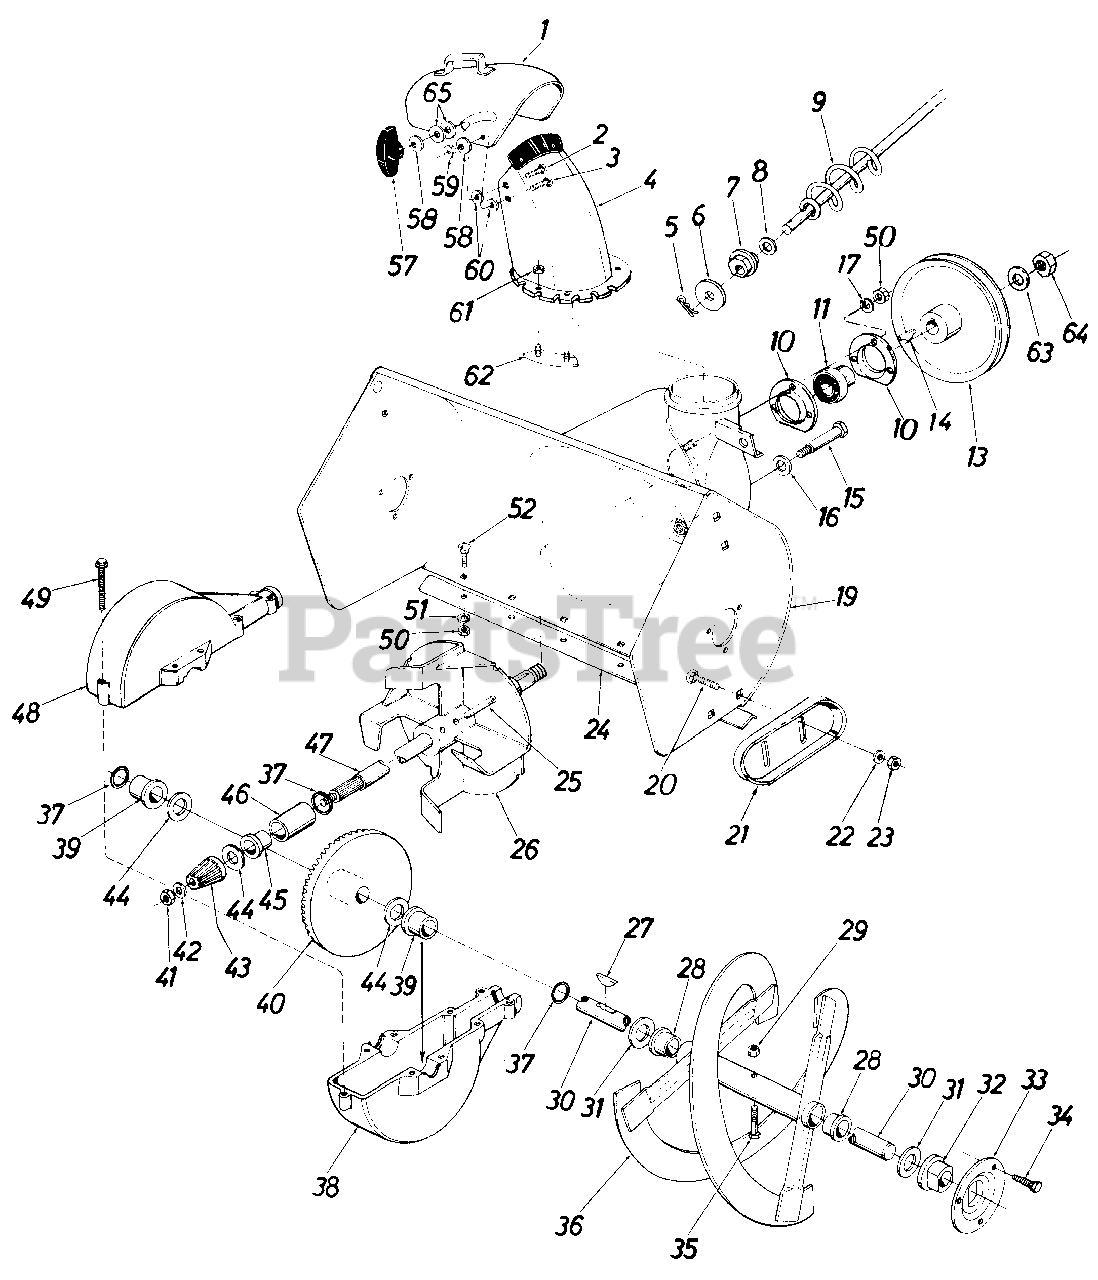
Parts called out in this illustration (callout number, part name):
1	Top Chute Ass'y.
2	Carriage Bolt 5/16-18 x 1.00" Lg.*
3	Carriage Bolt 5/16-18 x .62" Lg.*
4	Chute Ass'y.
6	Fl-Wash. .390 I.D. x 1.50" O.D.
8	Fl-Wash. .385 0 I.D. x .62" O.D.
9	Chute Crank Ass'y.
10	Bearing Housing
11	Self-Align Brg. w/ Collar .75" I .D.
13	1/2" "V"-Pulley .625" I.D. x 7.50" O.D.
14	#61 Hi-Pro Key 3/16" x 5/8" Dia.
15	Shld. Bolt .50" Dia. x 2.11" Lg.
16	Bell-Wash. .40" I.D. x .88" O.D. x .06
17	L-Wash. 5/16" I.D.*
19	24" Blower Housing Ass'y.
20	Carriage Bolt 3/8-16 x .62" Lg.*
21	Slide Shoe
22	Bell-Wash. 3/8" I.D.
23	Hex Jam Nut 3/8-16 Thd.
26	11" Dia. Blower Fan Ass'y.
27	#9 Hi-Pro Key 3/16 x 314" Dia.
28	Flange Brg. .75" I.D. x .88" O.D. x .62
29	Hex Ins. L-Nut 5/16-18
30	Spiral Axle
31	Fl-Wash. .75" I.D. x 1.50" O.D. x .06
32	Flange Brg. w/ Flats .755"
33	Bearing Housing
34	Hex Wash. Hd. Self-Tap Scr. 5/16-24 x .50" Lg.
35	Hex Bolt 5/16-18 x 1.50" Lg.
36	24" Spiral Ass'y. L.H.
37	"O"-Ring 3/4" I.D.
38	Bevel Gear Housing Lower Half
39	Plastic Flange Brg. .755" I.D.
41	Hex Cent. L-Nut 5/16-24 Thd.
42	Fl-Wash. .34" I.D. x .62 " O.D. x .06
43	Pinion Gear
44	Fl-Wash. .75" I.D. x 1.25" O.D. x .06
45	Flange Brg. .755" I.D.
46	Sleeve Brg. .755" I.D.
48	Bevel Gear Housing Upper Half
49	Hex Wash. Hd. Self-Tap Scr. 1/4-20 x 1.00" Lg.
50	Hex Nut 5/16-18 Thd.*
51	Bell-Wash. .34" I.D. x .88" O.D.
52	Carriage Bolt 5/16-18 x .62"*
57	Knob
58	Bell-Wash. .34" I.D. x .88" O.D.
59	Hex Cent. L-Nut 5/16-18 Thd.
60	Fl-Wash. .53" I.D. x 1.25" O.D. x .100
61	Hex Cent. L-Nut 1/4-20 Thd.
62	Chute Flange Keeper Ass'y.
63	Fl-Wash. .64" I.D. x .94" O.D. x .06
64	Hex Jam Nut 5/8-18 Thd.
65	Fl-Wash. .344 I.D. x 1.125 O.D.
